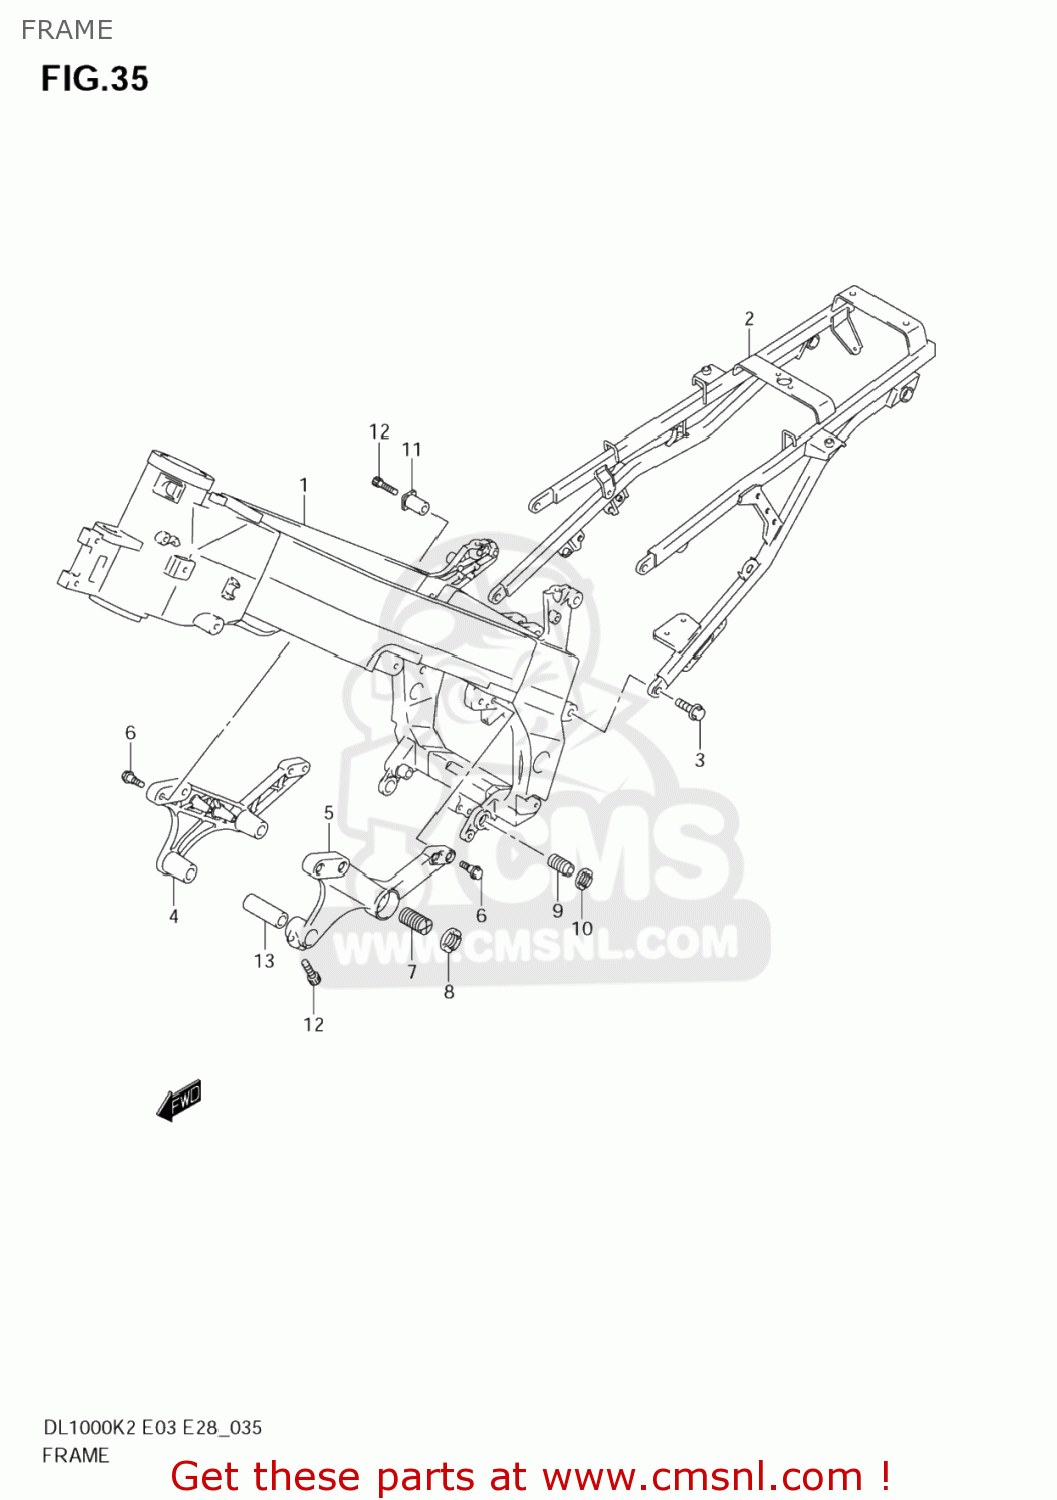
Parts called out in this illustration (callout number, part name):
1	FRAME COMP
2	RAIL,SEAT
3	BOLT
4	BRACKET,ENGINE MOUNTING,R
5	BRACKET,ENGINE MOUNTING,L
6	BOLT(8X30)
7	BOLT,CRANKCASE ADJUST
8	NUT,CRANKCASE ADJUST
9	BOLT,CRANKCASE ADJUST
10	NUT,CRANK CASE ADJUST BOLT
11	SPACER,MOUNTING RR UPR,R
12	BOLT
13	SPACER,ENG HEAD MTG FR,L
